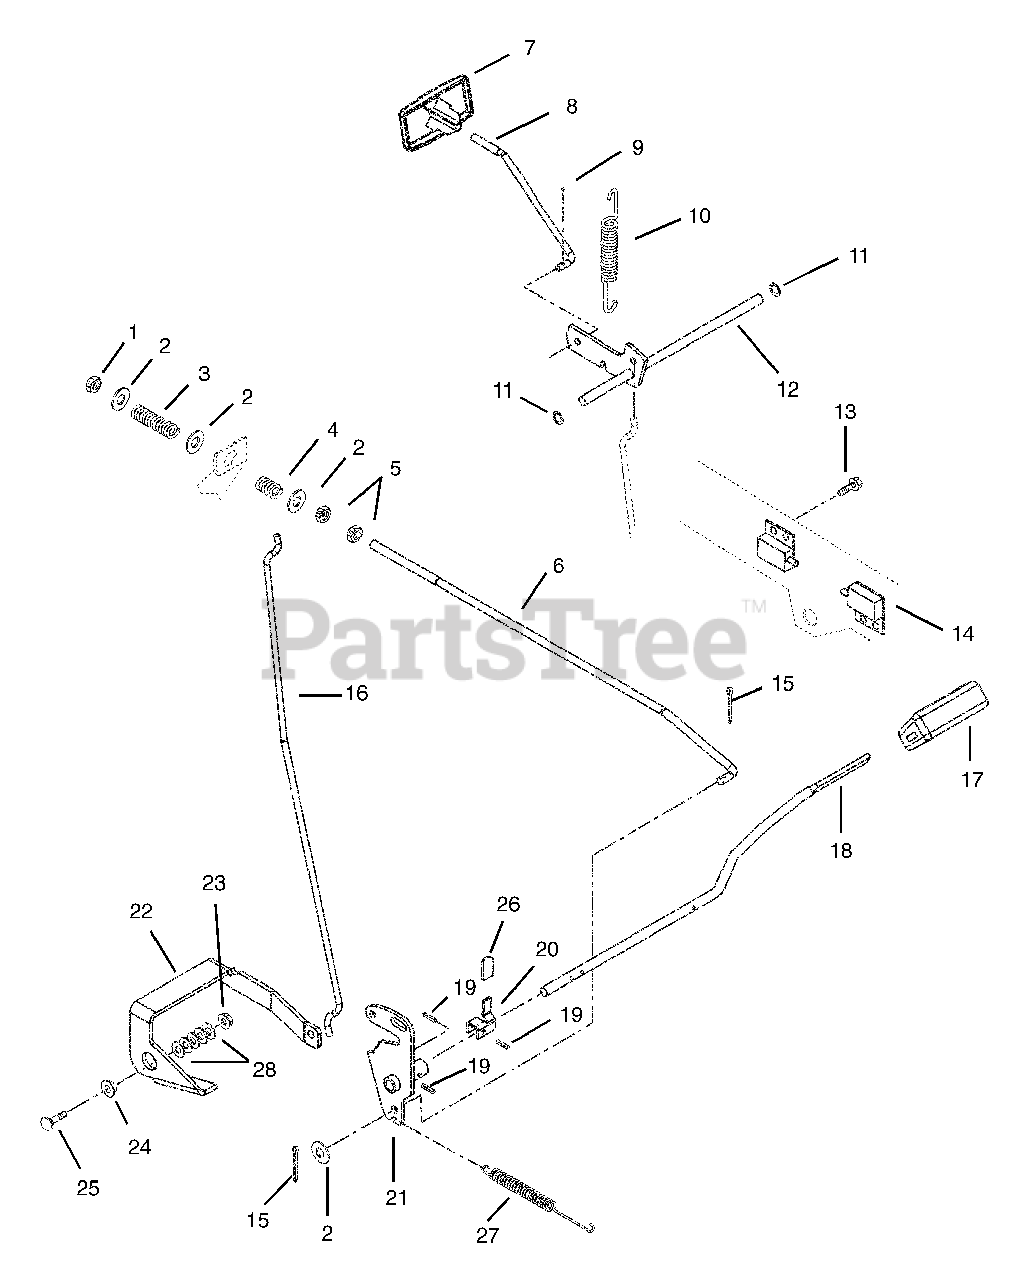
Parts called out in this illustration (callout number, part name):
1	@NUT-LK-CTR-JAM .375-16 YWZC
2	@WSHR-FL-STL.406X.812X.065 YWZ
3	SG-COMP .048X.59X2.06 WLD9
4	SG-COMP .125X.78X1.00 YWZ
5	NUT-HEX-JAM .375-16 YWZC
6	ROD - BRAKE
7	KNOB, PARK BRAKE
8	ROD, PARKING BRAKE
9	PIN-COTR .06X.50
10	SG-TENS .051X.60X2.25 WLD 7.0
11	RG-RTNG-EXT .250X.010
12	BELLCRANK-PARKING BRAKE
13	@SCR-TAP 12-24X.50 HWH TR YWZC
14	SWITCH- SINGLE POLE N.O.
15	@PIN-CTR .09X.75 EXTPRSQCT YWZ
16	ROD, PARKING BRAKE
17	COVER - PEDAL - BRAKE
18	PEDAL - BRAKE
19	PIN-GRV .188X1.25 TP A
20	LEVER - BRAKE SWITCH
21	ARM + HUB - BRAKE
22	LEVER, PARKING BRAKE
23	@NUT-LK-CTR .31-18 YWZC
24	BSHG, FLG .325X.499X.26X.88
25	BLT-RDHDSQSHK.31-18X.75 GR2 YW
26	GRIP .062 X .375 X 1.000 RE
27	SG-TENS .105X.85X5.00 WLD 40
28	WSHR-PLASTIC .390X.875X.062
